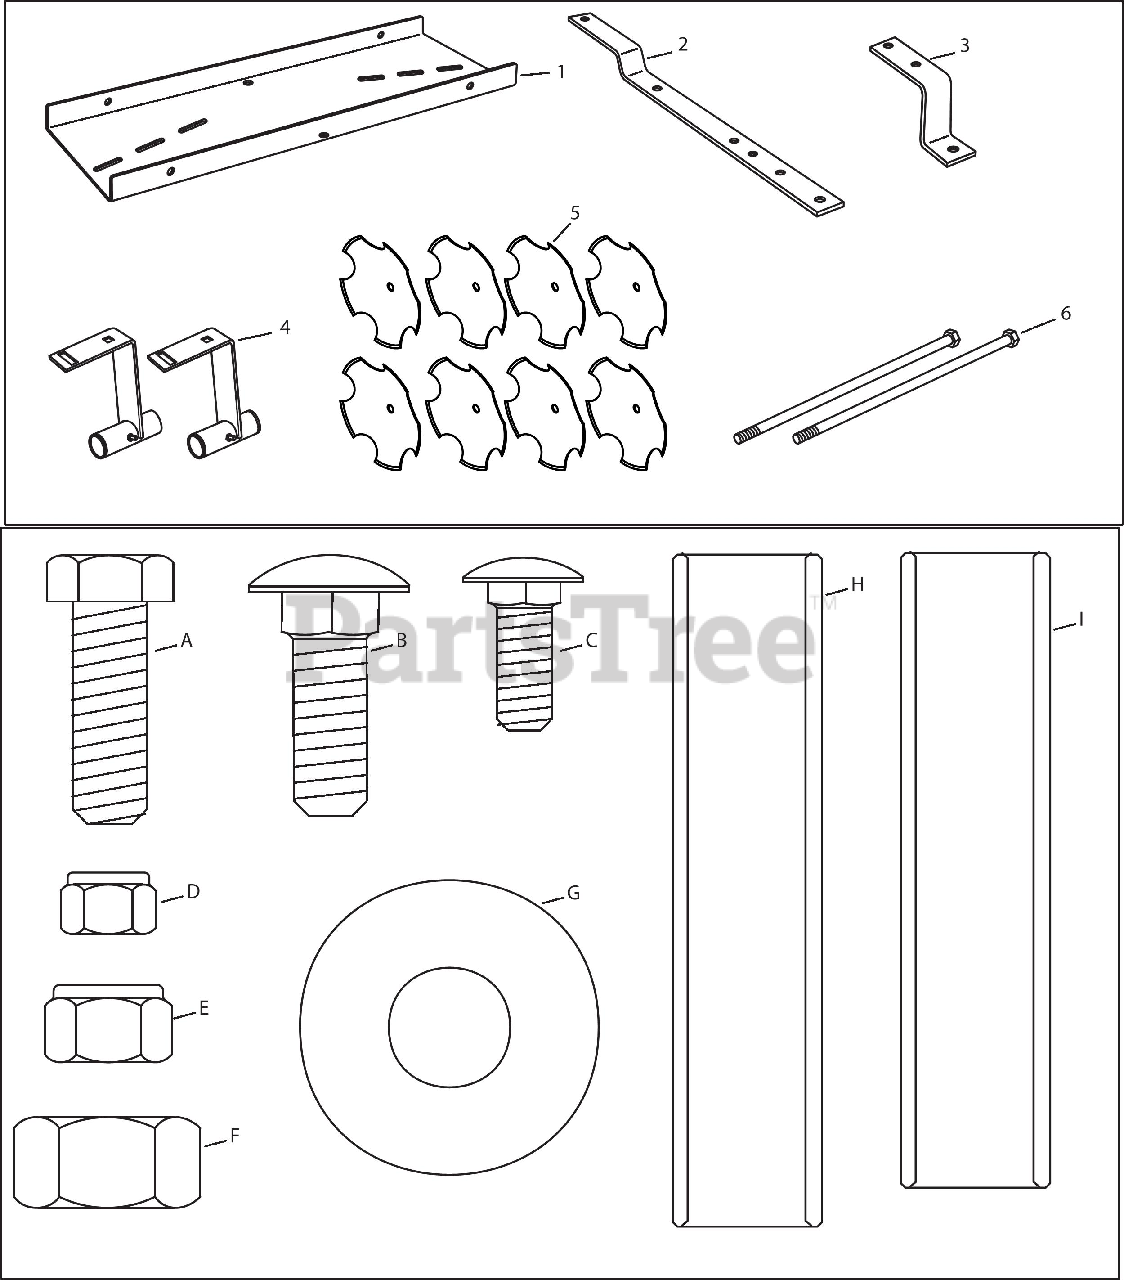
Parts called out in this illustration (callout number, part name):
3	Hitch Bracket
4	Bearing Hanger Bracket
5	Disc Blade
6	Hex Bolt, 3/4" x 16"
A	Hex Bolt, 1/2" x 1-1/2" Lg.
B	Carriage Bolt, 1/2" x 1-1/2"
C	Carriage Bolt, 3/8" x 1" Lg.
D	Nylock Nut, 3/8"
E	Nylock Nut, 1/2"
F	Hex Nut, 3/4"
G	Flat Washer, 3/4"
H	Bearing Sleeve
